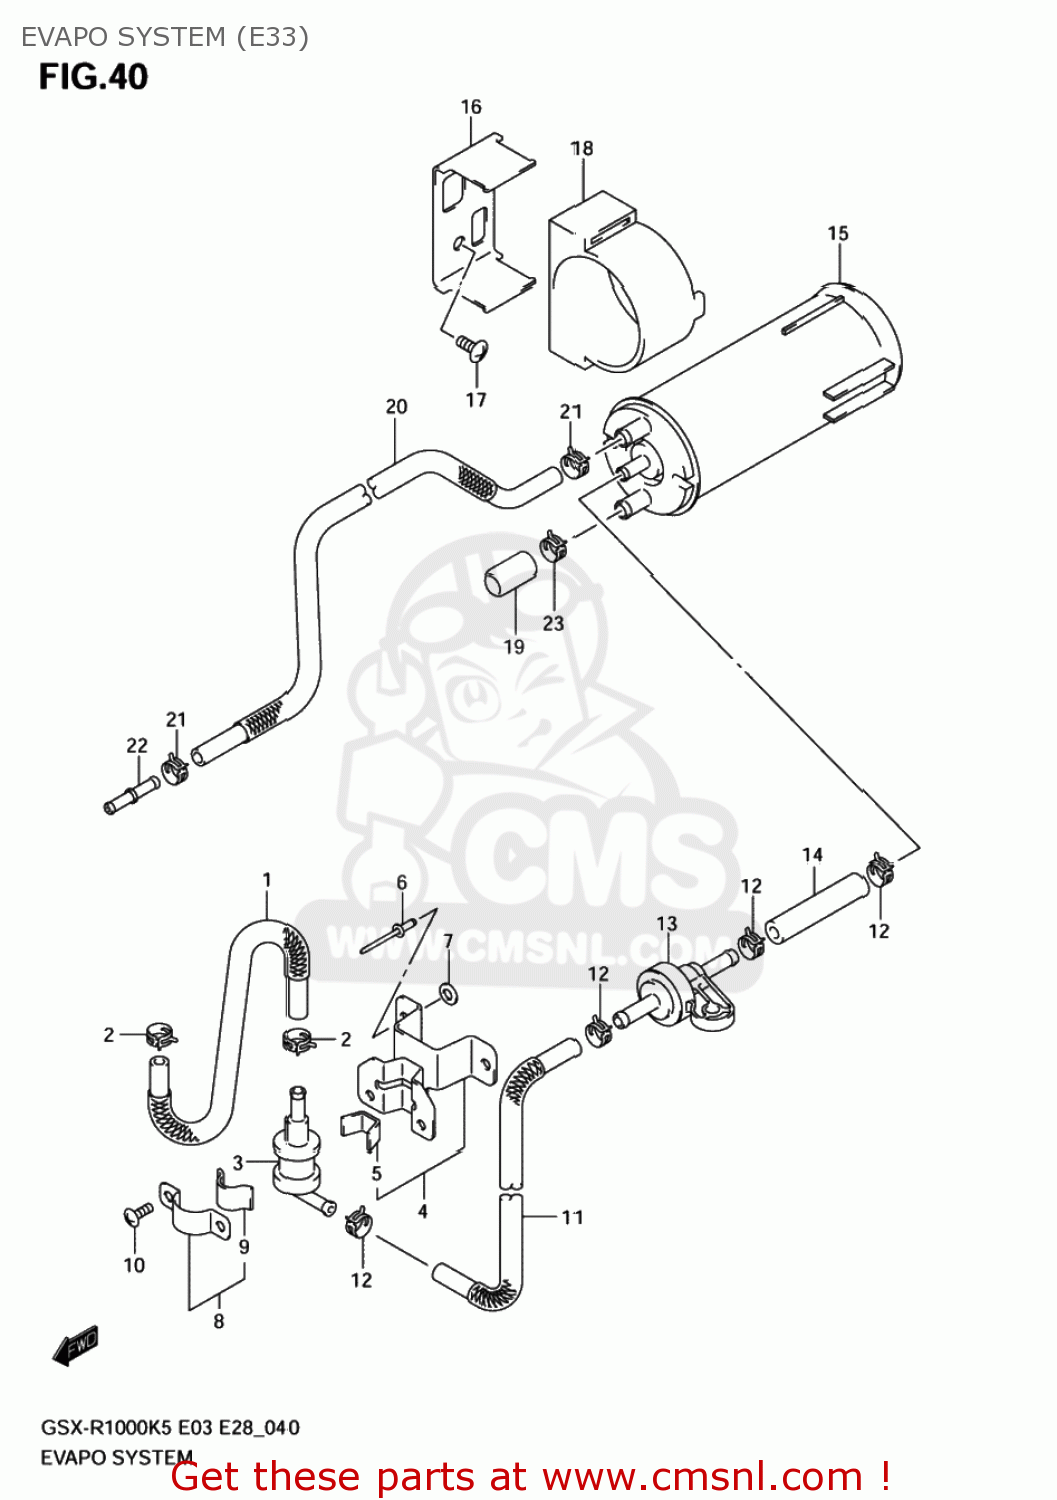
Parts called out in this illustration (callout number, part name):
1	HOSE,TANK & BREATHER VALVE
2	CLIP
3	VALVE,FUEL TANK BREATHER
4	PLATE,BREATHER VALVE
5	CUSHION
6	RIVET
7	WASHER
8	PLATE,FUEL TANK BREATHER NO.2
9	CUSHION
10	SCREW
11	HOSE,BRTHR VALVE & 2 WAY VALVE
12	CLIP
13	VALVE,2 WAY & BREATHER VALVE
14	HOSE(5.4X11.4X600)
15	CANISTER ASSY,CHARCOAL
16	BRACKET,CANISTER
17	SCREW(5X16)
18	CUSHION,CANISTER
19	CAP,OD:11.5
20	HOSE,CSTR PURGE
21	CLIP
22	JOINT
23	CLIP
